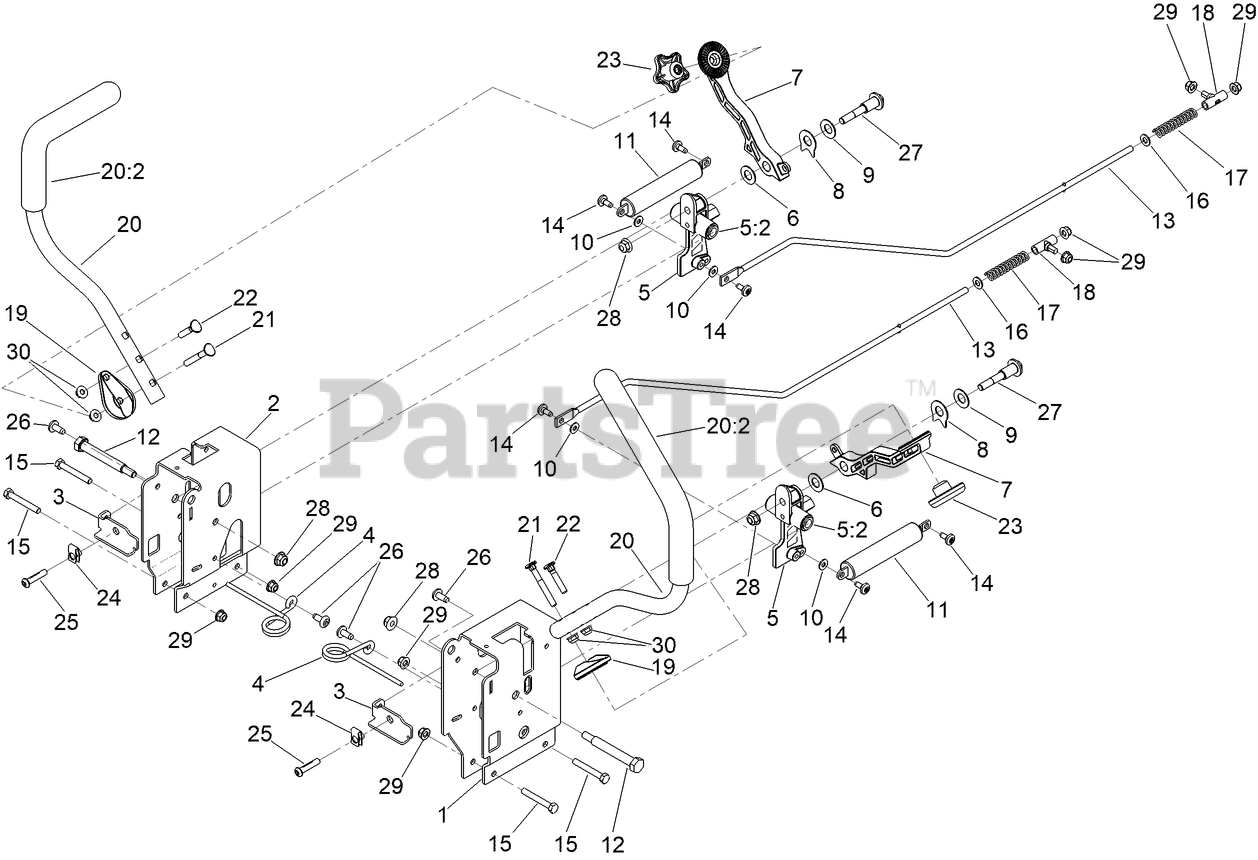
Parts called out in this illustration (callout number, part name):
1	CONTROL BOX - LH G7
2	CONTROL BOX - RH G7
3	ADJUSTMENT PLATE-CONTROL BOX
4	SPRING-TORSION
5	PIVOT ARM ASM
5:2	BUSHING-FLANGE
6	WASHER-NYLON
7	ARM-CONTROL, 32 TEETH
8	SPACER, ANTI-ROTATION
9	WASHER-BELLEVILLE
10	WASHER
11	DAMPER-NON CAVITATING
12	BOLT-PIVOT
13	ROD - HYDRO
14	SCREW-SHOULDER
15	SCREW-HH
16	WASHER-PLAIN
17	SPRING-COMPRESSION
18	MOUNT-ROD, HYDRO
19	DISC-ADJUSTMENT HANDLE, 32 TEETH
20	HANDLE-CONTROL,
21	SCREW-HANDLE
22	SCREW-HANDLE
23	KNOB-HANDLE
25	SCREW-HSBH
27	BOLT-PIVOT
28	NUT-HF, NI
29	NUT-HF, NI
30	NUT-HF
